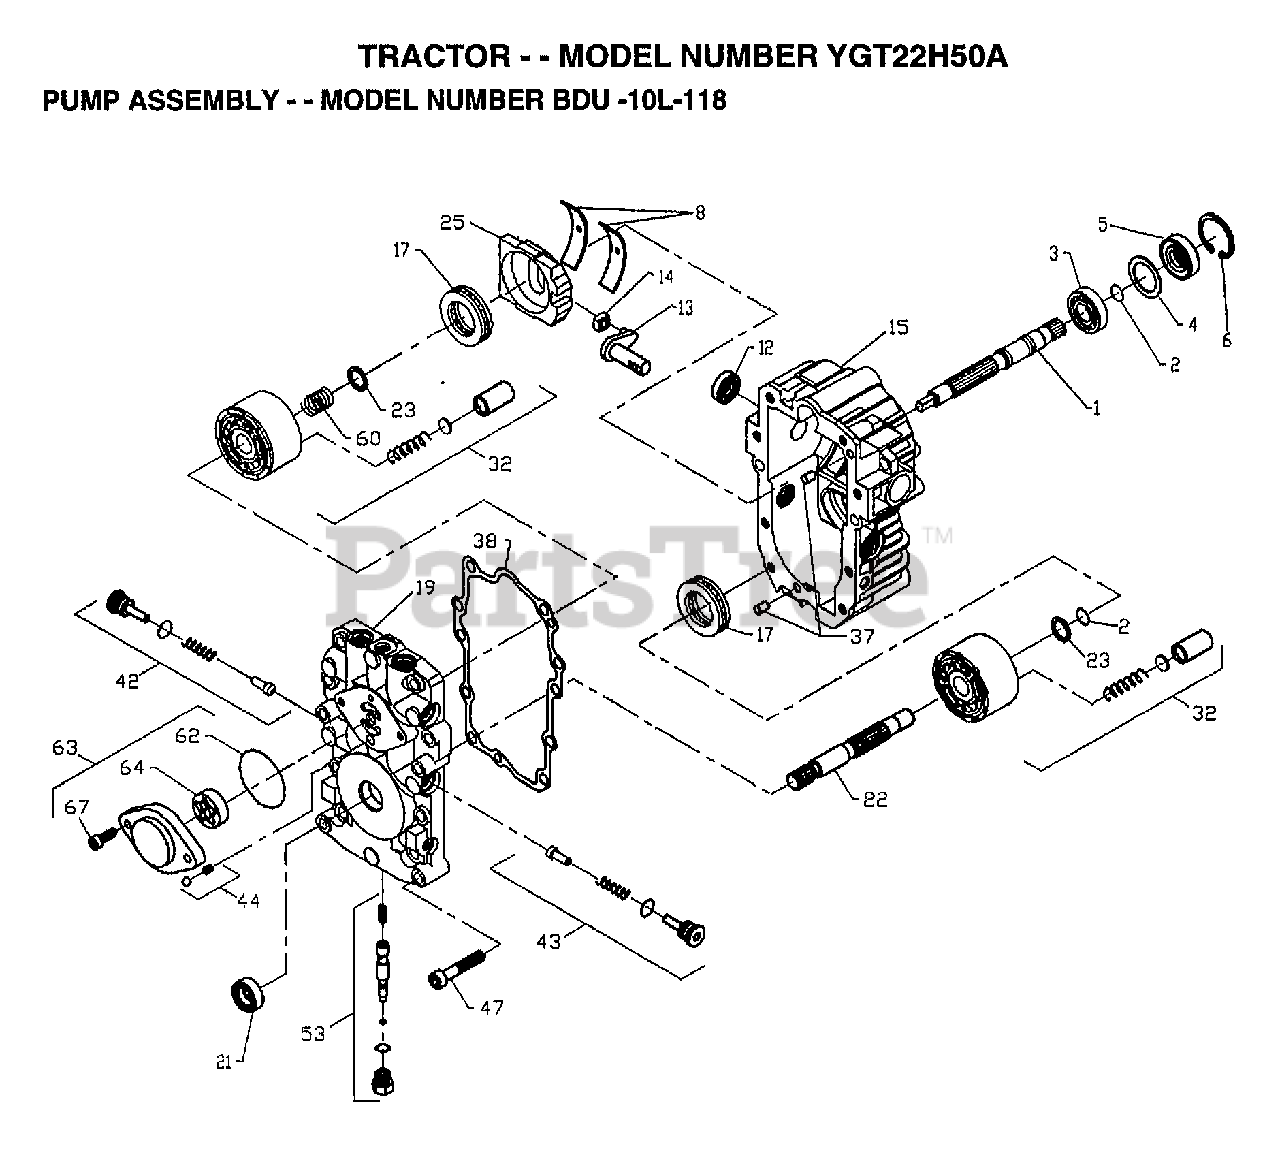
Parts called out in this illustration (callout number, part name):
1	SHAFT.PUMP.50158
2	RETAINIANG RING-(2003016)
3	BALL BEARING
4	SPACER
5	SEAL LIP
6	RING.RET.2003052
8	CRADLE BEARING (2003023)
12	SEAL.9008000-0126
13	TRUNION ARM (2003005)
14	GUIDE.2000015.HYD
15	KIT.HSG.2513035.
19	KIT.CENT.2513006
21	LIP SEAL-9008000-0127
22	SHAFT.MOT.2003034
23	WASHER.2003017
25	"SWASHPLATE,VARIAB"
32	BLOCK.CLYN.70079.
37	PIN
38	GASKET.20030600
42	KIT.VALVE.2510050
43	KIT.VALVE.2510050
44	KIT.RELI.2510011.
47	SCREW9007314-0808
53	"KIT,BYPASS VALVE"
60	SPRING.2003014.
62	0RING.90041011340
63	KIT.CHARG.2513027
64	GEROTOR.J1041008
67	SCREW.CAP.50095.
